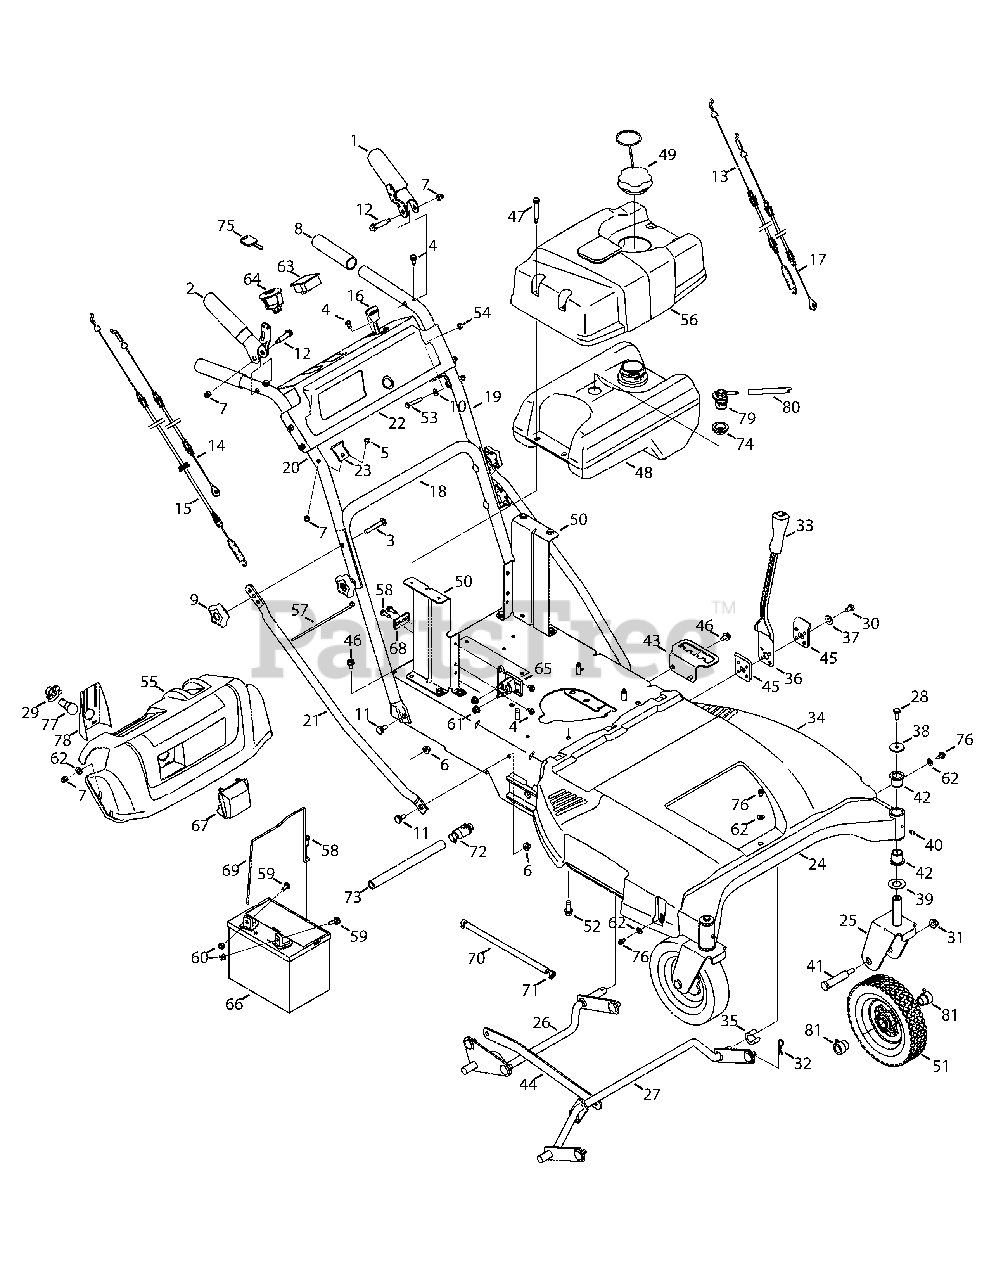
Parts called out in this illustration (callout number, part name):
1	Lever Assembly - LH
2	Lever Assembly - RH
3	Screw, Carriage, 5/16-18 x 2.25
4	Screw, 1/4-20 x 0.500
5	Screw, Cap, 1/4-20 x 1.50
6	Nut, Flange Lock, 5/16-18
7	Nut, Lock Cap, 1/4-20
8	Grip, 1.0 ID x 5.0 Lg
9	Star Knob, 5/16-18
10	Washer, Bell, .265 x .75 x .062
11	Screw, Shoulder, .435 x .178-5/16
12	Screw, Shoulder, .375 x 1.355, 1/4-20
13	Cable, Clutch Wheel
14	Cable, Brake, Transmission - RH
15	Cable, Clutch Deck
16	Cable, Throttle/Choke, 38 x 1.1
17	Cable, Brake, Transmission - LH
18	Lower Handle
19	Upper Handle - LH
20	Upper Handle - RH
21	Brace Tube
22	Handle Panel
23	Cable Mount Bracket - RH
23	Cable Mount Bracket - LH
24	Frame Assembly
25	Caster Wheel Bracket Assembly
26	Deck Lift Assembly, RR
27	Deck Lift Assembly, Front
28	Screw, HH Cap, 5/16-24 x .750
29	Lamp Socket
30	Screw, HH Cap, 5/16-18 x .50
31	Nut, Flange Lock, 3/8-16
32	Click Pin, .092 x 1.64
33	Handle Grip
34	Belt Cover
35	Snap Spacer, .63 ID x .75 LG
36	Deck Height Lever
37	Washer, Bell, .340 x .872 x .060
38	Washer, Flat, .330 x 1.25 x .120
39	Washer, Flat, .760 ID x 1.50 OD
40	Lube Fitting, 3/16
41	Bolt, Shoulder, .625 x 2.515 x 3/8-16
42	Flange Bearing, .760 x .941 x 1.0
43	Height Adjustment Bracket
44	Link Pivot Bracket
45	Lever Pivot Bracket
46	Screw, TT, 5/16-18 x .625
47	Screw, Shoulder, .32 x 1.8 x 1/4-20
48	Fuel Tank, 2 Gal.
49	Fuel Cap
50	Fuel Tank Mounting Bracket
51	Wheel, 8 x 1.75
52	Screw, TT, 3/8-16 x 1.25
53	Screw, HH Cap, 1/4-20 x 1.75
54	Nut, Hex, 1/4-20
55	Handle Panel
56	Tank Cover
57	Cable Tie
58	Screw, TT, 1/4-20 x .75
59	Screw, 1/4-20 x .75
60	Nut, Sems, 1/4-20
61	Nut, Flange Lock, 1/4-20
62	Washer, Flat, .25 x .63 x .0515
63	Hour Indicator Meter
64	Key Switch
65	Solenoid, 12V
66	Battery
68	Shift Adjust Plate
69	Battery Hold Down
70	Fuel Hose
71	Hose Clamp
72	Oil Drain
73	Oil Drain Hose
74	Rubber Gromet
75	Key, Ignition, Black
76	Screw, 1/4-20 x 1.75
77	Lamp
78	Label Reflector
79	Rollover Valve
80	Vent Hose
81	Flange Bearing w/ Fitting
